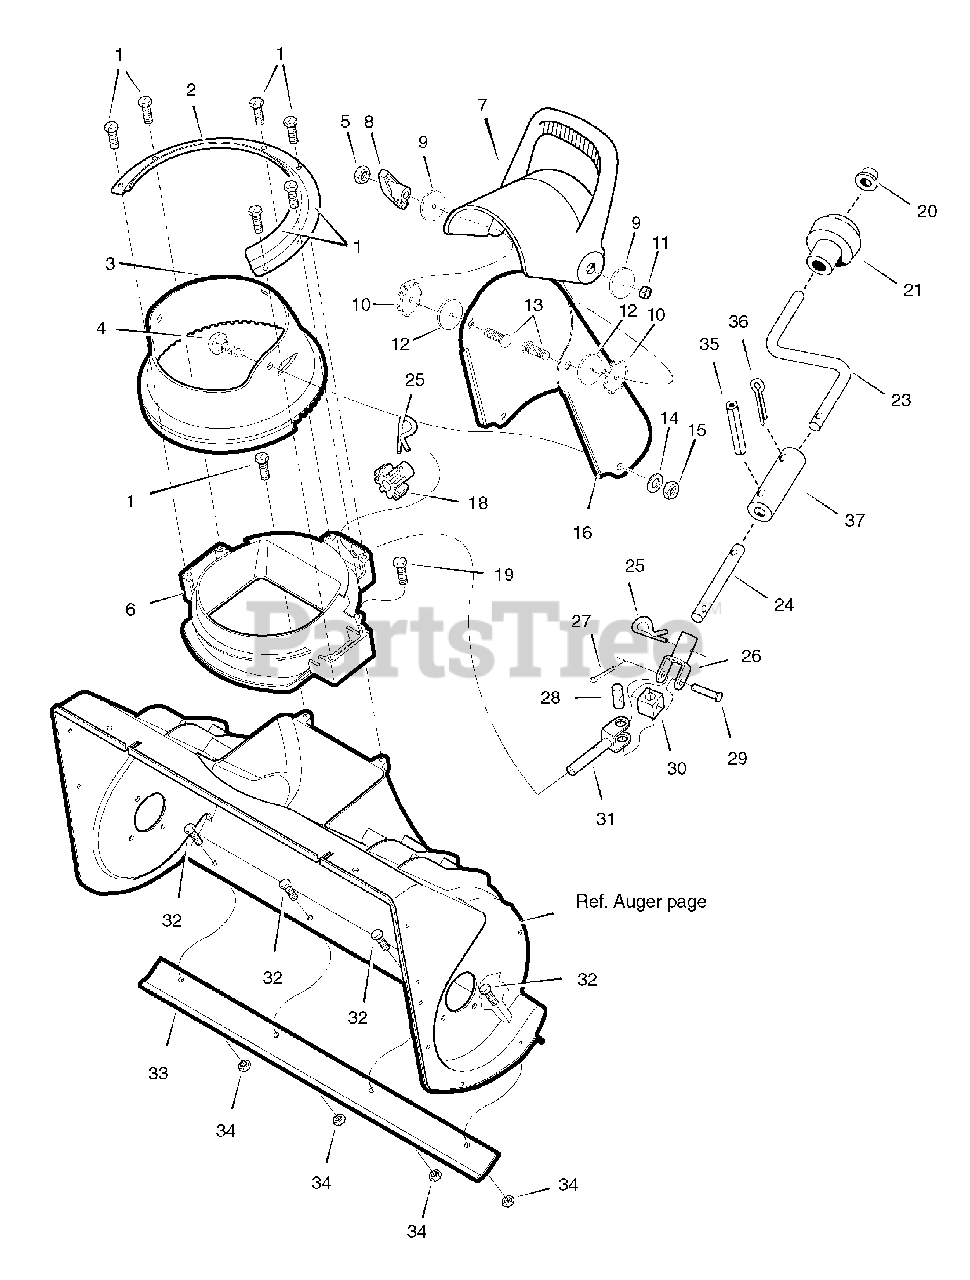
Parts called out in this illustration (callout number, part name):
1	SCREW 1/4-14
2	RETAINER, Chute Ring
3	RING, Chute
4	BOLT, Carriage 5/16-18 x .75
5	NUT 5/16-18 Reghex
6	NECK, Chute
7	CHUTE, 22" Upper
8	T-KNOB, 3.00 Plastic
9	WASHER, Flat 1 - 1/2 O.D
10	LOCKWASHER, Shakeproof
11	LOCKNUT, Hex 5/16-18
12	WASHER, Rubber 1-1/2 O.D
13	BOLT, Upper Chute
14	WASHER, Flat 13/32 x 13/16
15	NUT, 5/16-18 Hex, Nylock
16	CHUTE, Lower
18	GEAR, 9-Tooth
19	SCREW, 1/4-14 x 3/4
20	NUT, Push
21	KNOB, Crank
23	CRANK, Chute Rotation
24	HANDLE, Chute Rotator Lower
25	PIN, Hair
26	YOKE ASSEMBLY, Adapter
27	PIN, Cotter
28	PIN, Universal Joint
29	PIN, Clevis
30	HOUSING, Universal
31	ROD, Lower Crank
32	SCREW 1/4-20 x 3/4
33	BLADE, Scraper
34	LOCKNUT, Hex 1/4-20
35	PIN, Spring 5/32 x 1.00
36	CLIP, Hairpin 3/32 x 1.625 Black
37	CHUTE HANDLES, Splice
